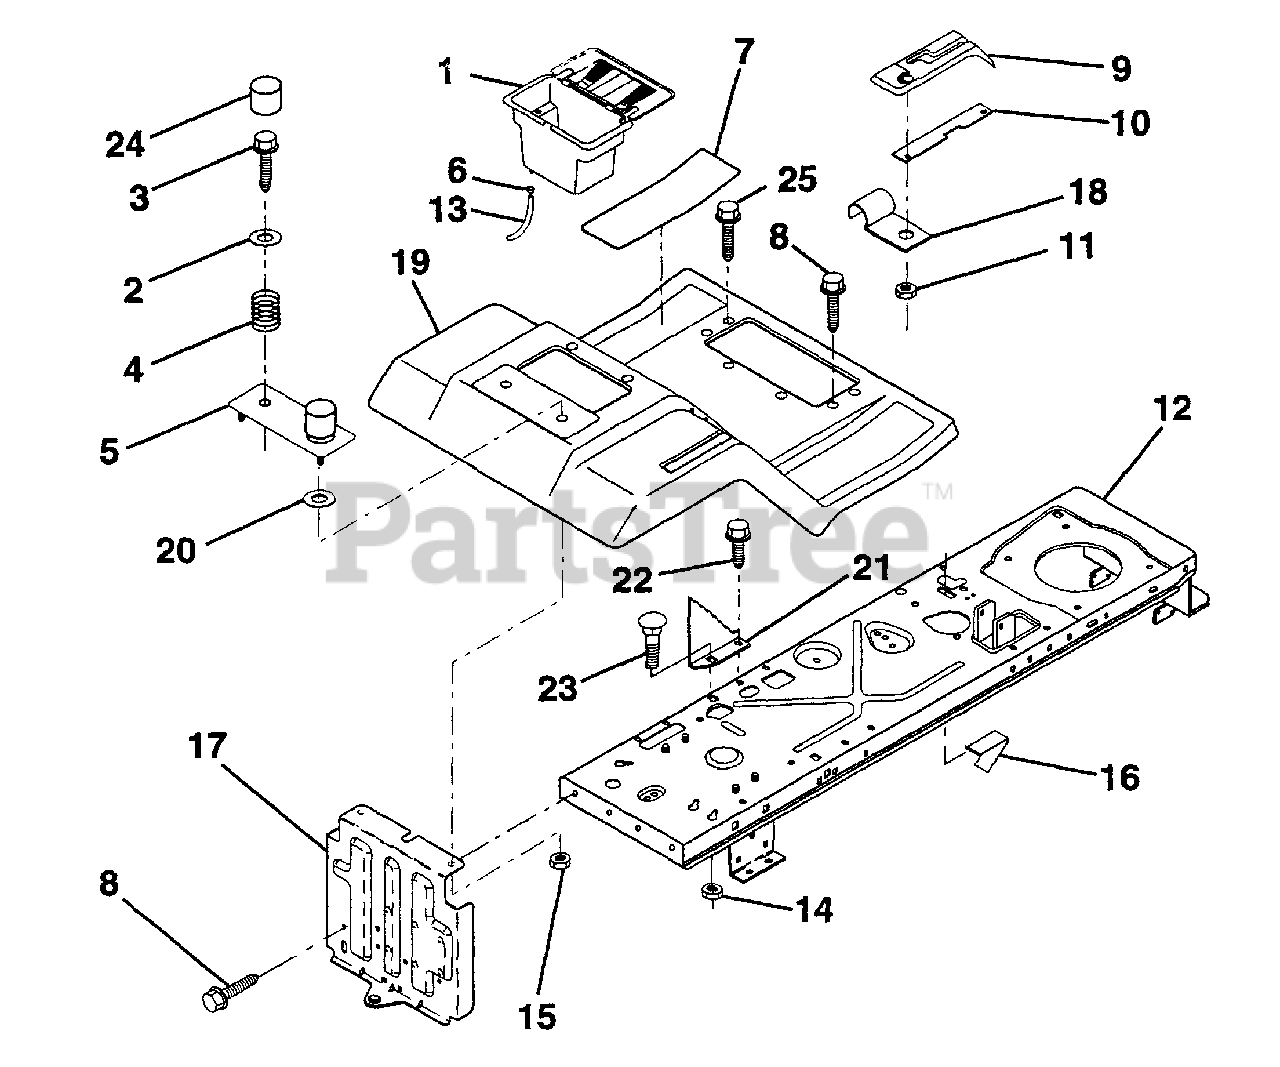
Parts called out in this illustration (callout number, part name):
1	Case Asm. Battery
2	Washer 13/32 x 1-1/4 x 12 Ga.
3	Screw Thdrol. 3/8-16 x 3/4
4	Spring seat
5	Plate Asm. Pnt Battery Fender
6	Clamp Hose Olive
7	Pad Footrest Rubber Deluxe
8	Screw Thdrol. 5/16-18 x 3/4
9	Console Shf. 6sp W/Ign.
10	Plate Lock Shift
11	Nut Self Thd. Wsh-Hd 1/4
12	Chassis Asm. Weldment
13	Tube Plastic
14	Nut Crownlock 5/16-18
15	Nut Keps Blk Hex 1/4-20
16	Switch Actuator
17	Drawbar Asm.
18	Clip Insulated
19	Fend/Foot Asm. Pnt Shf. Fnd.
20	Washer 9/32 x 7/8 x 13 Ga.
21	Bracket Stop Depth
22	Screw Thdrol 5/16-18 x 1/2
23	Bolt Rd hd sqnk. 5/16-18 x 3/4
24	Cap Spring Seat
25	Scr-Hex S.T. 5/16-18 x 1
